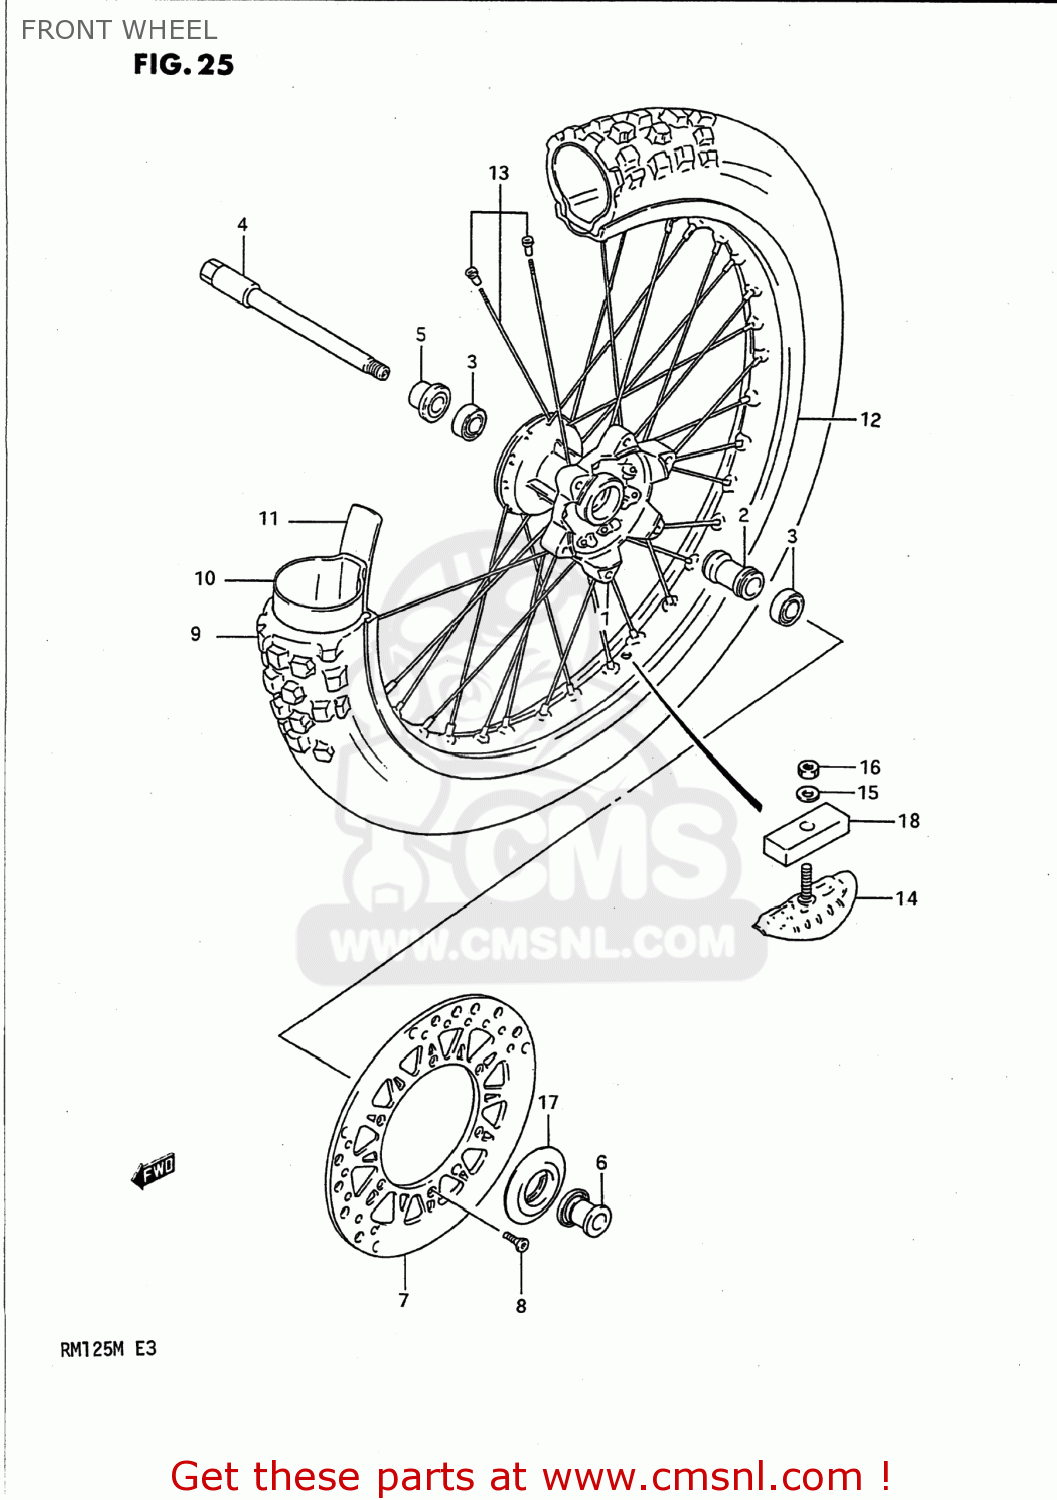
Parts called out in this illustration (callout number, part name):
1	HUB,FRONT
2	SPACER,FR HUB BEARING
3	BEARING
4	AXLE,FRONT
5	SPACER,FR AXLE,R
6	SPACER,FRONT AXLE,LEFT
7	DISC,BRAKE
8	SCREW
9	TIRE,FRONT
10	TUBE,INNER
11	PROTECTOR,WHEEL INNER
12	RIM,FRONT WHEEL (1.60X2
13	SPOKE SET,FRONT
14	STOPPER,BEAD
15	WASHER
16	NUT
17	CAP,FR HUB,L
18	CUSHION,BEAD STOPPER
